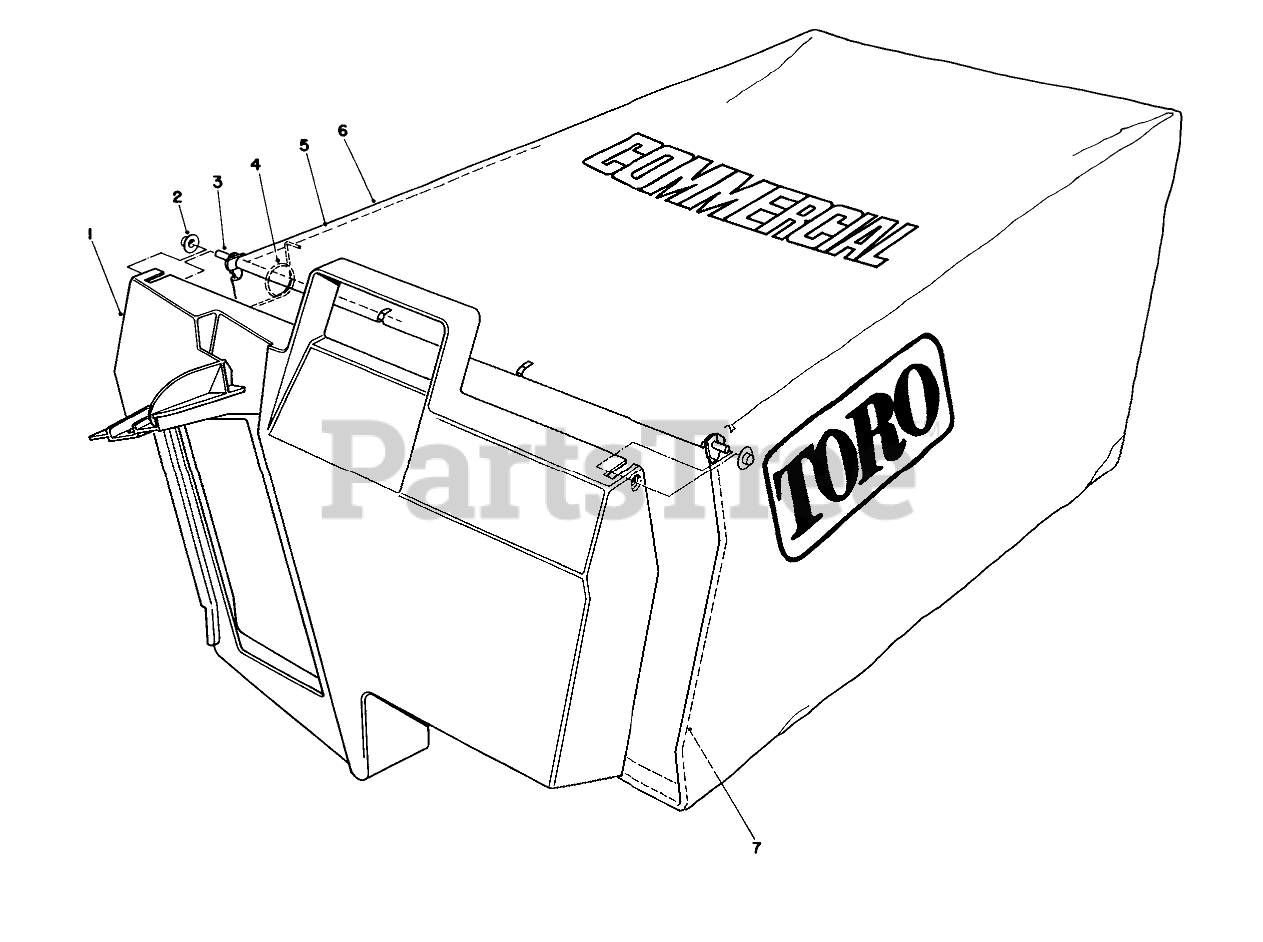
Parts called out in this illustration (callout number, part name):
1	DOOR-BAG, GRASS
2	NUT-PUSH
3	HINGE-DOOR, BAG
4	SPRING
5	FRAME-BAG, UPPER
6	Bag
7	FRAME-BAG
